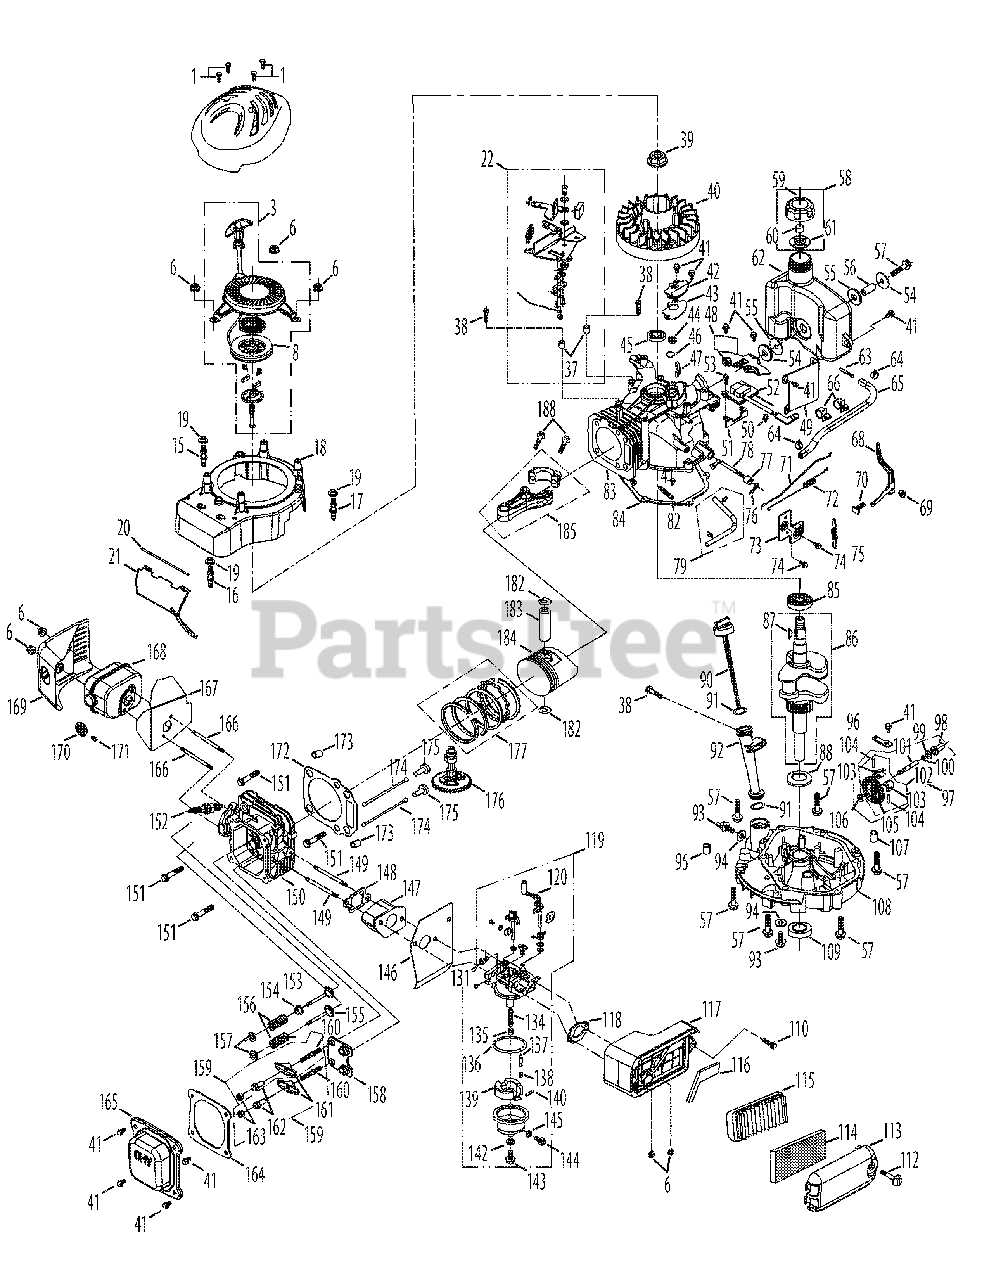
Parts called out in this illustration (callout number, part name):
1	Self-Tapping Bolt, #12-16 x 1.0"
3	Recoil Starter Assembly
6	Nut M6 X 10 Mm
7	Rope Return Spring
8	Starter Pulley
15	Starter/Shroud Stud M6x85-48
16	Starter/Shroud Stud M6x87-51.5
17	Starter/Shroud Stud M6x79
18	Inner Shroud
19	Engine Shroud Spacer
20	Air Vane Shaft
22	Brake Assembly
37	Brake Spacer
38	Bolt M6×35
39	Flywheel Nut M14
41	Bolt M6×14
42	Breather Cover Plate
43	Breather Gasket
44	Breather Spring
45	Lower Crankshaft Seal
46	Breather Valve
47	Breather Screen
48	Fuel Tank Bottom Bracket
49	Tank/Label Bracket
50	Plastic Clamp 6.3×8
51	Ignition Coil Bracket
52	Ignition Coil Assembly
53	Bolt M6×18
54	Fuel Tank Washer
55	Rubber Bushing
56	Fuel Tank Bushing
57	Tank/Sump Bolt M8x50
58	Fuel Cap Assembly
59	Fuel Cap
60	Foam Insert
61	Vent Gasket
62	Fuel Tank Assembly
63	Fuel Filter
64	Fuel Hose Clamp
65	Fuel Hose
66	Plastic Support Clamp
68	Governor Arm Bracket
69	Governor Arm Nut M6
70	Governor Arm Bolt
71	Throttle Linkage
72	Throttle Linkage Spring
73	Component Bracket
74	Bolt M6×12
75	Governor Spring
76	Governor Cotter Pin
77	Governor Seal
78	Governor Arm Shaft
79	Breather Hose Assembly
82	Flexible Clamp
83	Crankcase Complete
84	Crankcase Cover Gasket
85	Main Bearing
86	Crankshaft Assembly
87	Woodruff Key
88	Crankshaft Thrust Washer
90	Dipstick
91	Dipstick / Oil Fill Tube O-Ring
92	Oil Fill Tube
93	Oil Drain Plug
93	Oil Plug
94	Oil Drain Plug Washer
94	Oil Plug Washer
95	Crankcase Cover Dowel 9×14
96	Governor Gear Mounting Plate
97	Governor Gear/Shaft Assembly
107	Crankcase Cover Dowel 7×14
108	Crankcase Cover - dual drain
109	Lower Crankshaft Seal
110	A/F Base Bolt M6×30
112	Air Filter Cover Thumb Screw
113	Air Filter Cover
114	Air Cleaner Kit
115	Air Filter
117	Inner Air Cleaner Housing
118	Carburetor Gasket Plate
119	Carburetor Assembly
120	Choke & Throttle Shaft Dust Seals
131	Idle Speed Adjusting Screw
134	Main Nozzle / Emulsion Tube
135	Main Jet
136	Fuel Bowl O-Ring
137	Needle Valve (Float)
138	Needle Valve Spring
139	Float
140	Float Pin
142	Fuel Bowl Gasket
143	Fuel Bowl Mounting Bolt
144	Fuel Drain Plug
145	Fuel Drain Plug Gasket
146	Carburetor Gasket
147	Carburetor Insulator
148	Carburetor Insulator Gasket
149	Carb Stud M6x113
150	Cylinder Head
151	Head Bolt M8×54
152	Spark Plug/F6rtc
153	Intake Valve
154	Valve Seal
155	Exhaust Valve
156	Valve Spring
157	Valve Spring Retainers
158	Push Rod Guide
159	Rocker Arm Assembly
160	Rocker Arm Stud
161	Rocker Arm
162	Fulcrum Nut
163	Jam Nut
164	Valve Cover Gasket
165	Valve Cover
166	Muffler Stud M6x95
167	Muffler Gasket
168	Muffler Assembly
169	Muffler Shield
170	Spark Arrestor
171	Spark Arrestor Screw
172	Cylinder Head Gasket
173	Cylinder Head Dowel 10×16
174	Push Rod Kit
174	Push Rod
175	Tappet
176	Camshaft Assembly
177	Piston Ring Set
182	Piston Pin Snap Ring
183	Piston Pin
184	Piston
185	Connecting Rod Assembly
188	Connecting Rod Bolt
